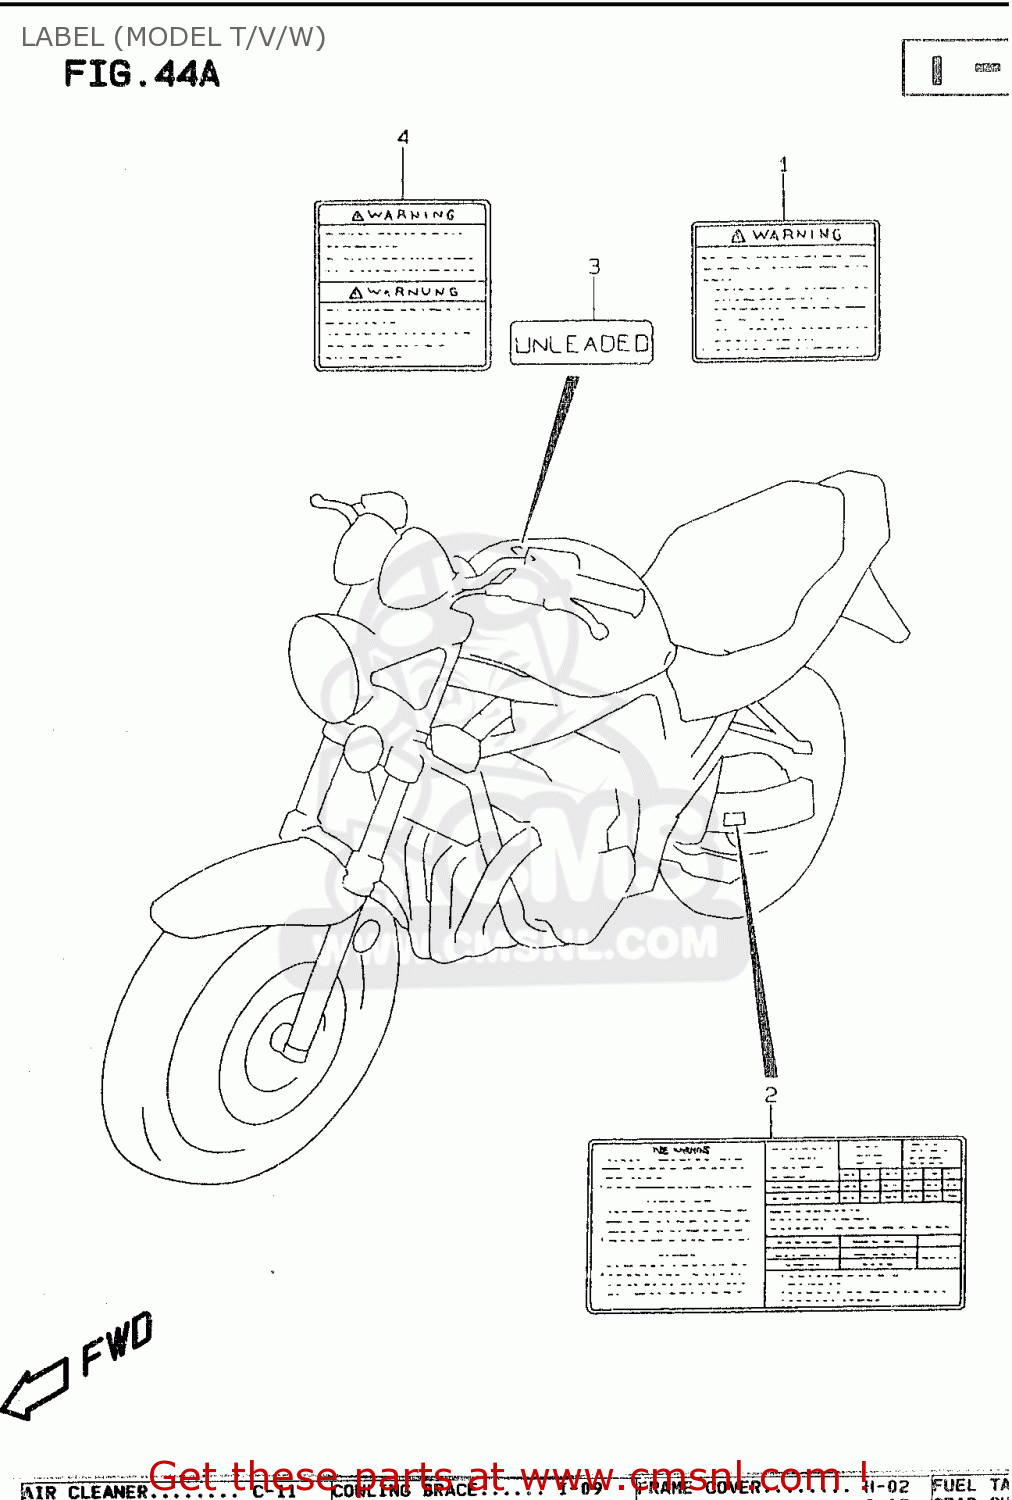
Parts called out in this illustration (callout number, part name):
1	LABEL,WARNING
2	LABEL,TIRE INFORMATION
3	LABEL,CAUTION
4	LABEL,WARNING STEERING
5	MANUAL, OWNER'S
